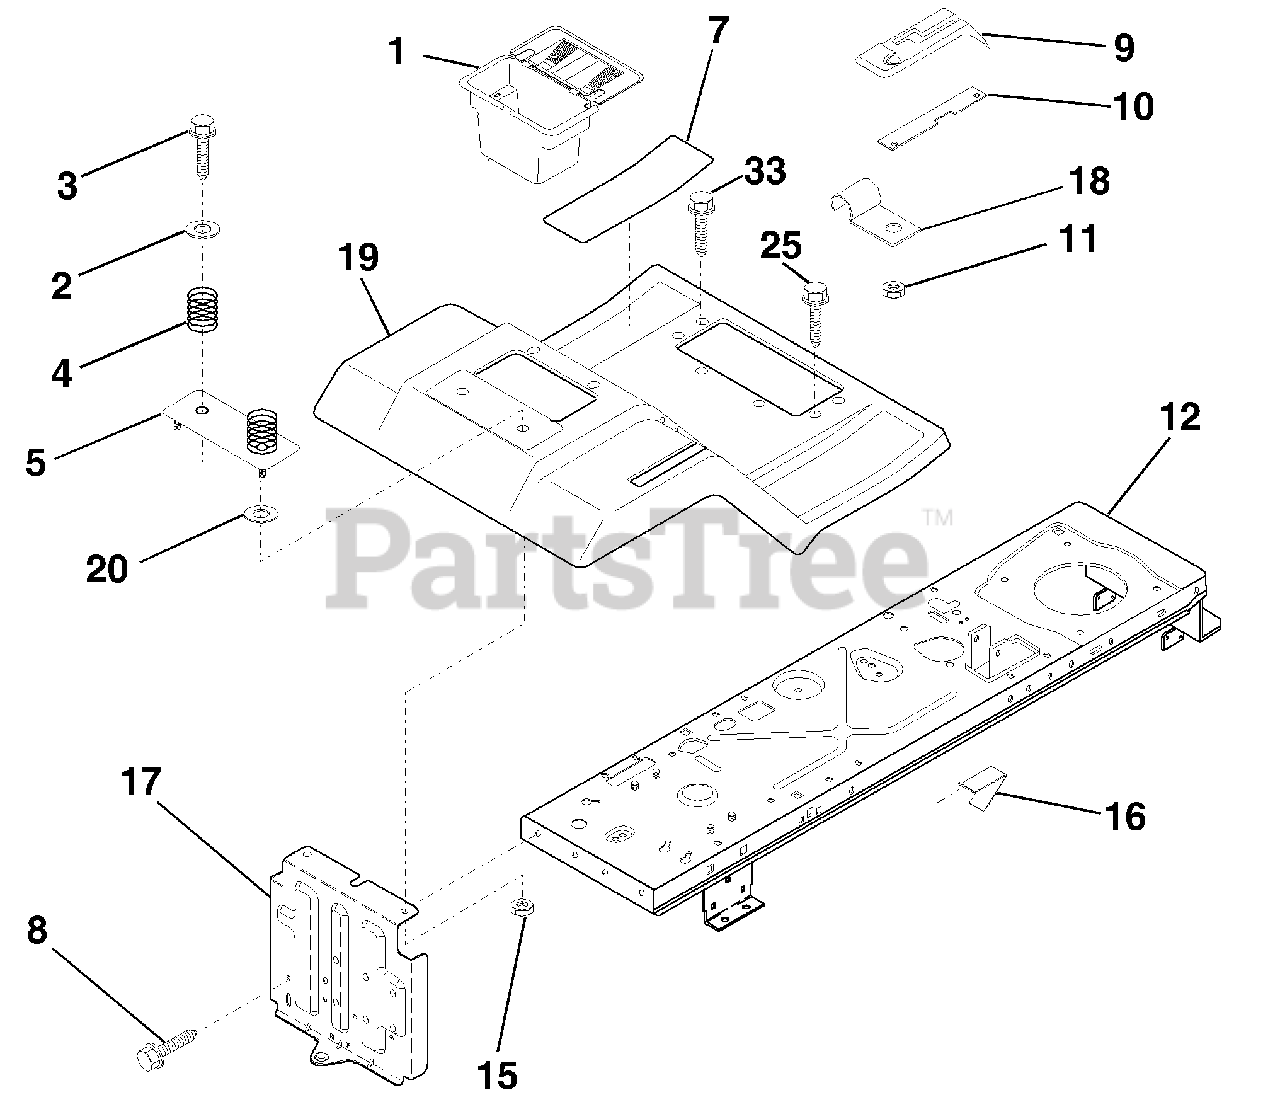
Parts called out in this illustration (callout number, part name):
1	Case, Battery
2	Washer 13/32 x 1-1/4 x 12 Ga.
3	Screw, Hex Wsh. Thrdrol. 3/8-16 x 3/4
4	Spring, Compression, Seat
5	Plate, Asm. Battery
7	Pad, Footrest
8	Screw, Hex Wsh Thdrol. 5/16-18 x 3/4
9	Console, Shift Control
10	Bar, Shift Lock
11	Nut, Self-Thrd., Wsh. Head 3/16
12	Assembly, Frame
15	Nut, Keps Hex 1/4-20 UNC
16	Switch Actuator
18	Clip, Insulated
19	Fender/Footrest
20	Washer 9/32 x 7/8 x 13 Ga.
25	Screw Tapping 5/16-18
33	Screw Hex Wsh Thdroll 5/16-18 x 1
